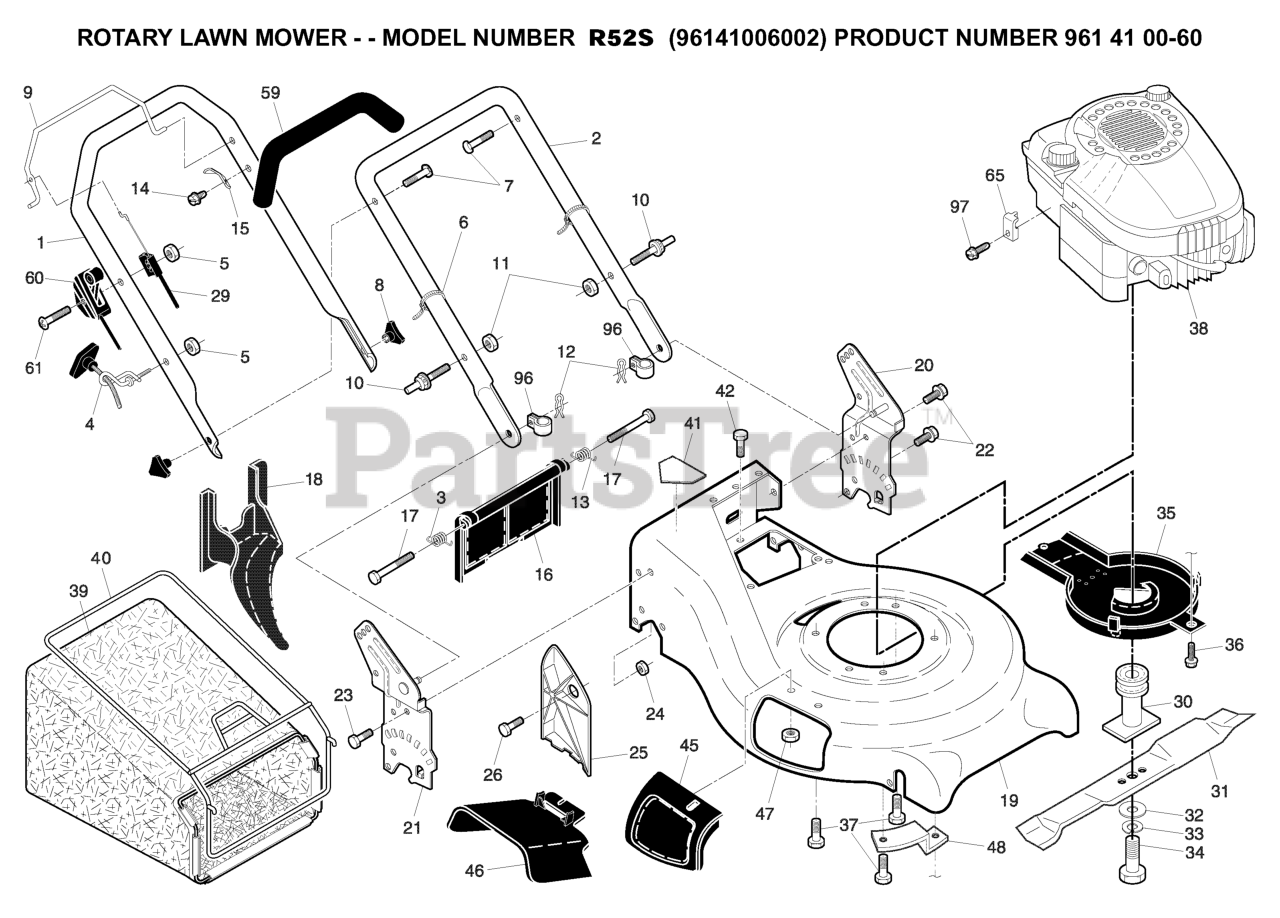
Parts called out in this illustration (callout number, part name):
1	HANDLE.UP.DLX.COMF.W/GRIP.GREY
2	HANDLE.LOWER.21.GREY
3	SPRING.RH.REAR.DOOR.21.RWGD
4	RB GUIDE.ROPE.STD.BLK.ZIN WSL
5	NUT
6	TIE GUIDE
7	BOLT, HANDLE 5/16-18X1.75
9	BAIL.CONT.COMF.PUSH.ORGANGE.RH
11	NUT.CENTERLOCK.5/16-
12	HAIRPIN COTTER
13	SPRING.LH.REAR.DOOR.21.RWGD
15	BRACKET UPSTOP
16	REAR DOOR ASSEMBLY
18	PLUG.MULCHER.RGD.21.
20	BRKT.ASM.HNDL.21.RWGD.LT
21	BRKT.ASM.HNDL
22	SELF-TAPPING SCREW 5/16-18X3/4
23	BOLT, HEX HEAD 5/16-18
24	NUT.71038.31-18.HEX.NYLOCK
25	CLIPPING DEFLECTOR
29	ENGINE ZONE CONTROL
30	BLADE ADAPTOR / PULLEY
31	BLADE.21.PUSH
32	WASHER,HARDEN
33	LOCKWASHER
34	SCREW, HEX HD 3/8-24 X 1-3/8
35	DEBRIS SHEILD
36	SCREW.HEX.WSH
37	BOLT 3/8-16X1-1/8
40	FRAME, GRASSBAG
41	DECAL.INTERNATIONL.CUTFINGER
45	MULCHER DOOR ASM.
46	DEFLECTOR, DISCHARGE
48	BRACKET
59	GRIP.HANDLE.FOAM
60	CONTRL.THROTTLE.
65	CABLE CLAMP(ENGINE)
96	CLIP.CABLE.BLK
97	SCREW.HEX.HEAD.WASHER.10-16
